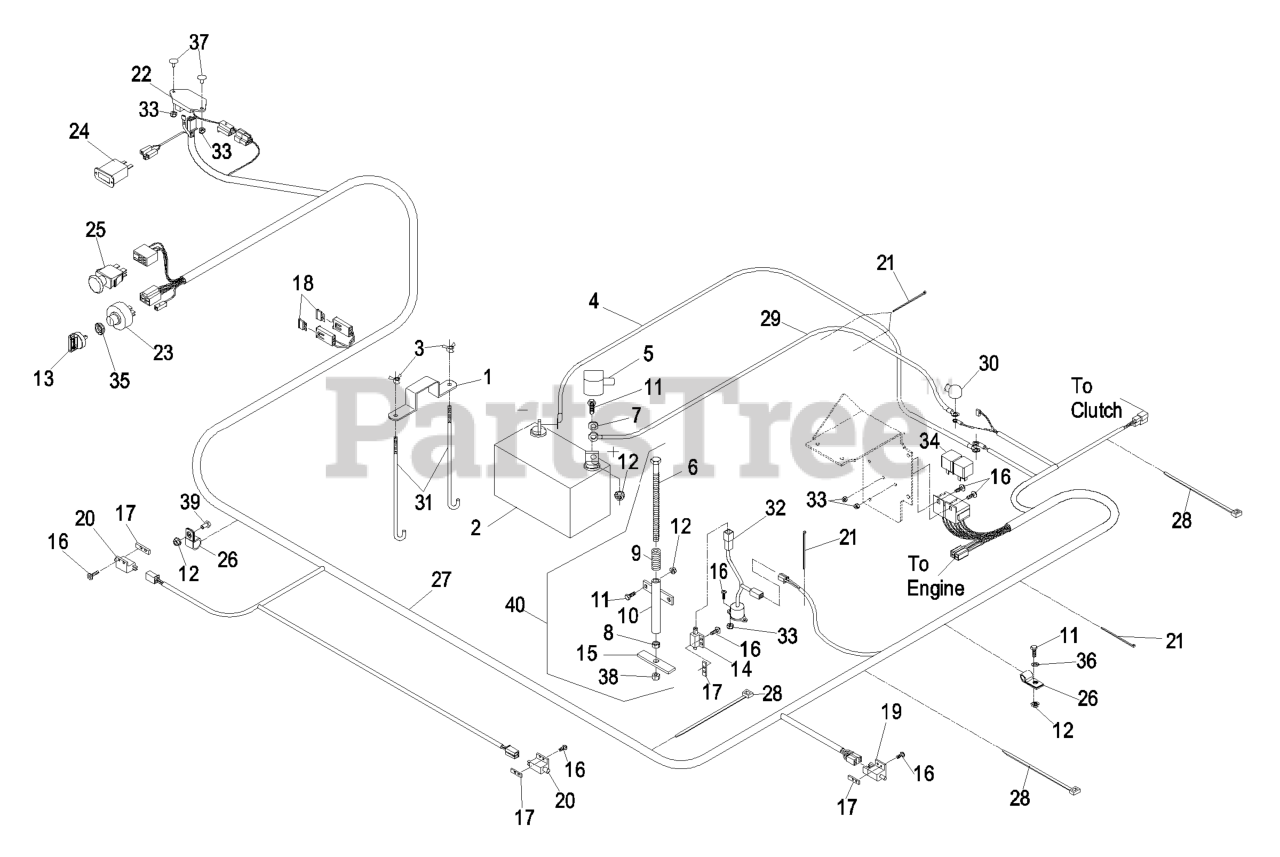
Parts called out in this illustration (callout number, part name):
1	STRAP-HOLDDOWN
3	WINGNUT
4	WIRE-GROUND
6	SCREW-HH
7	WASHER-FLAT
8	NUT-HEX
9	SPRING-SWITCH, SEAT
10	MOUNT-SPRING, SEAT
11	SCREW-HH
13	KEY-IGNITION
14	SWITCH-CLOSED, NORMALLY
15	PLATE-SWITCH, SEAT
16	SCREW-PPH
17	PLATE-TAPPED
18	FUSE-BLADE TYPE, 20 AMP
20	SWITCH-OPEN, NORMALLY
21	TIE-CABLE
22	MODULE-DELAY, SEAT
24	METER-HOUR
25	SWITCH-PTO
26	CLIP-LOOM
27	HARNESS,WIRE LAZER KC
28	TIE-PLASTIC
30	INSULATOR-SOLENOID
31	BOLT-HOLDDOWN
33	NUT-LOCK, NI
35	NUT-SWITCH, IGNITION
36	WASHER-FLAT
37	BOLT-CARR
38	NUT-LOCK, NI
39	SCREW-HH
40	ASM,SEAT SWITCH ACTUATOR
